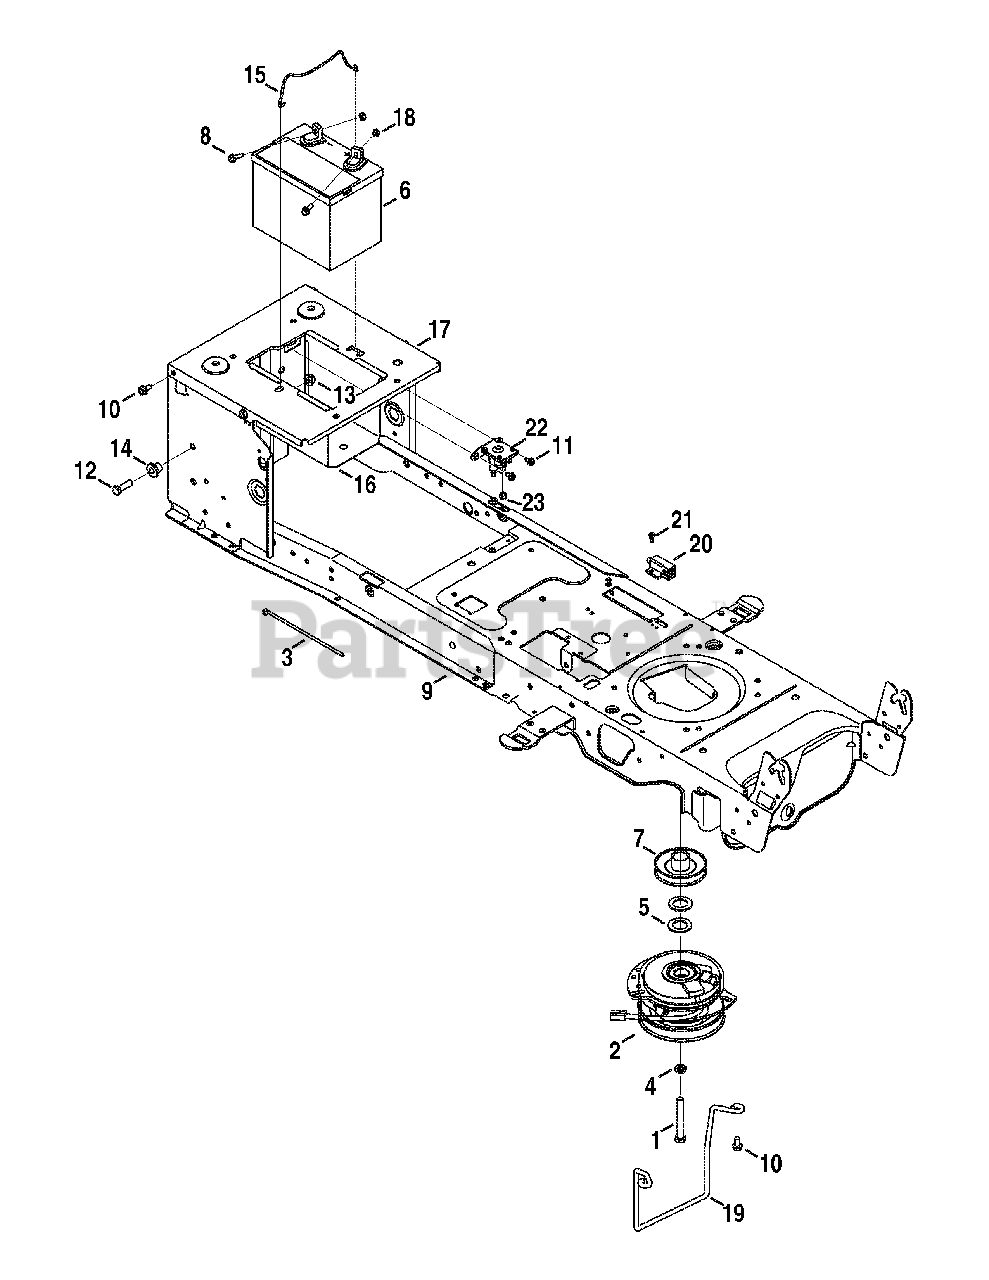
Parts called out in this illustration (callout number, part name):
1	Hex Head Screw, 7/16-20:3.50
2	Electric PTO Clutch
3	Cable Tie, 3/16 x .05 x 7.4
4	Lock Washer, 7/16
5	Flat Washer, 1.031 x 1.620 x .095
6	Battery
7	Electric PTO Engine Pulley
8	Hex Head Flange, 1/4-20:.75
9	Frame
10	Taptite Screw, Indented Washer, 5/16-18:.750
11	Taptite Screw, Indented Washer, 1/4-20:0.500
12	Hex Head Screw, 3/8-16:1.25
13	Flangelock Nut, 3/8-16
14	Shoulder Spacer, .38 X 1.0 X .70
15	Battery Holder Rod
16	Battery Tray
17	Seat Frame Bracket
18	Sems Nut, 1/4-20
19	Belt Keeper Rod
20	Interlock Switch
21	Shoulder Screw, #10-32:.500
22	Solenoid, 12 V
23	Flangelock Nut, 1/4-20
